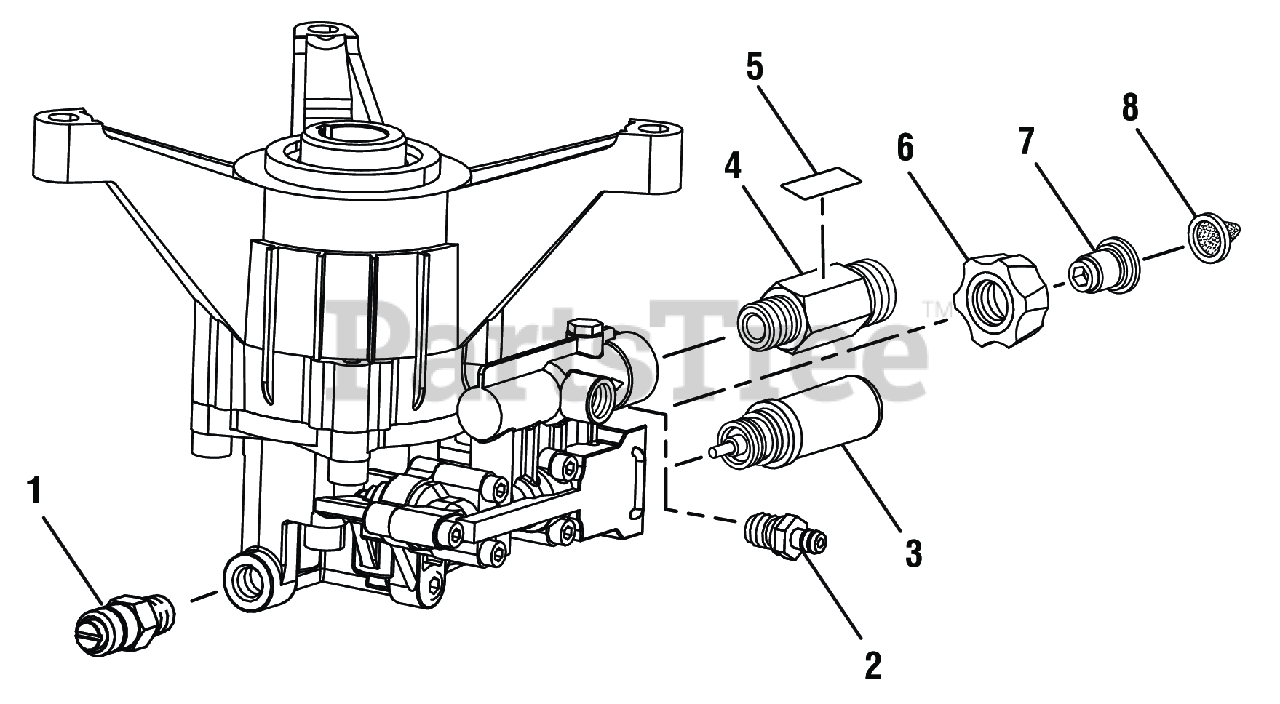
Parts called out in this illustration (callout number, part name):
1	Thermal Release Valve.
2	Detergent Injector Assembly
3	Unloader Valve Assembly
4	Outlet Tube
5	High Pressure Hose Outlet Label
6	Inlet Filter Adapter/Brass Insert
7	Inlet Filter Connector
8	Filter Screen (Pump Inlet)
